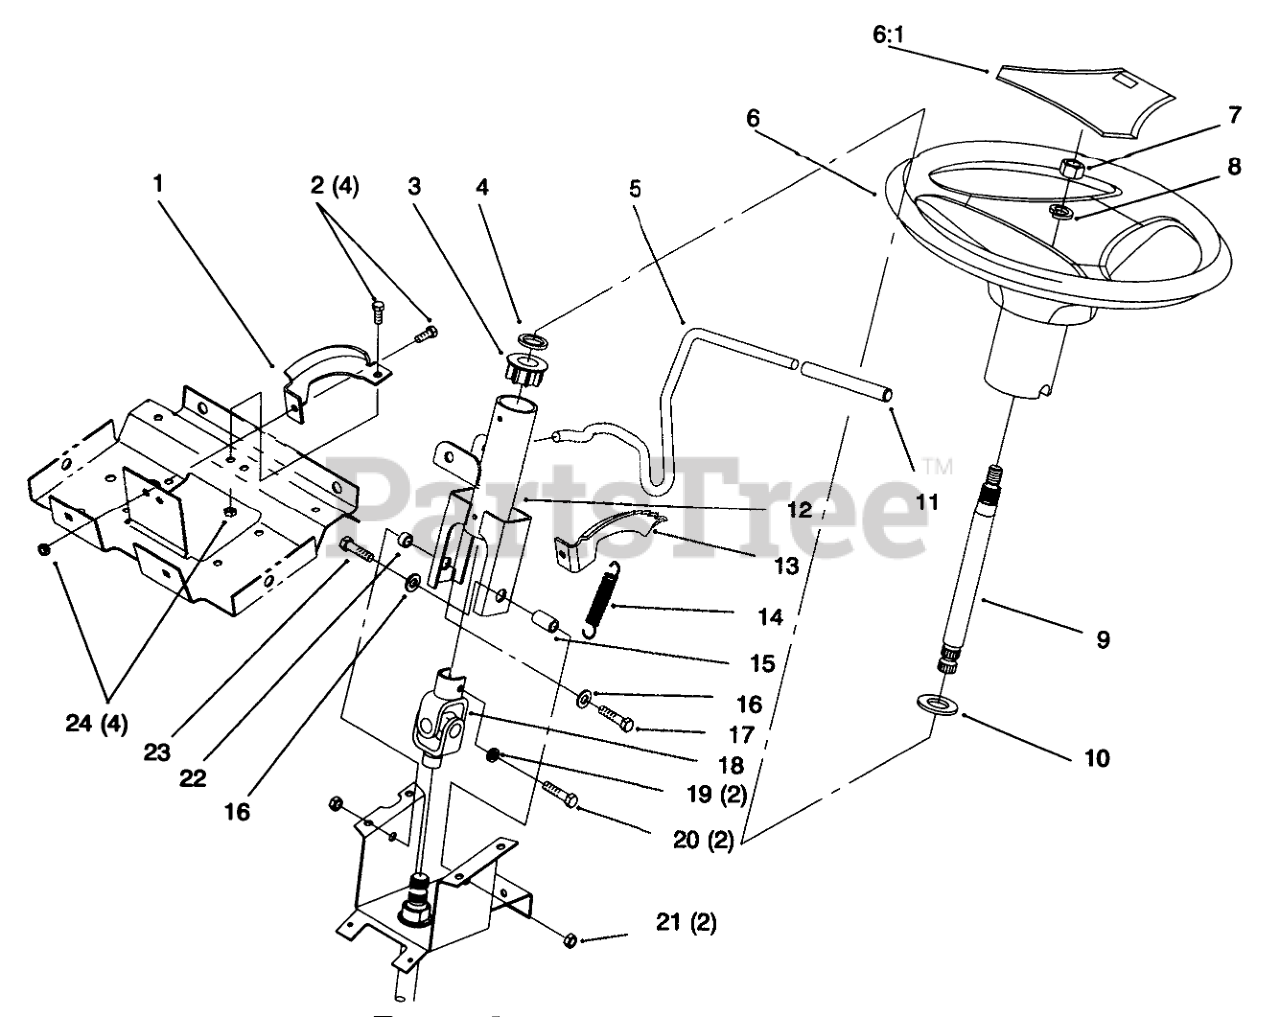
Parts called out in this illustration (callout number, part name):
1	BRACKET-SUPPORT, COLUMN
2	SCREW-HH
3	BUSHING-STEERING, UPPER
4	WASHER-BOWED
5	LEVER-TILT
6	Steering Wheel-14" (Only On: 72046)
6	Steering Wheel-Soft Touc (Only On: 72064)
6:1	COVER-WHEEL
7	NUT-HH
8	WASHER-LOCK
9	SHAFT-SHORT, STEERING
10	WASHER-FLAT
11	CAP-ROD, TILT
12	COLUMN ASM
13	BRACKET-DETENT
14	SPRING-EXTENSION
15	SPACER-YOKE
16	WASHER-PLAIN
17	SCREW-HH
18	U-JOINT, STEERING
19	WASHER-LOCK
20	SCREW-CAP, HH
21	NUT-LOCK, NI
22	SPACER-YOKE, RIGHT
23	SCREW-HH
24	NUT-HEX
